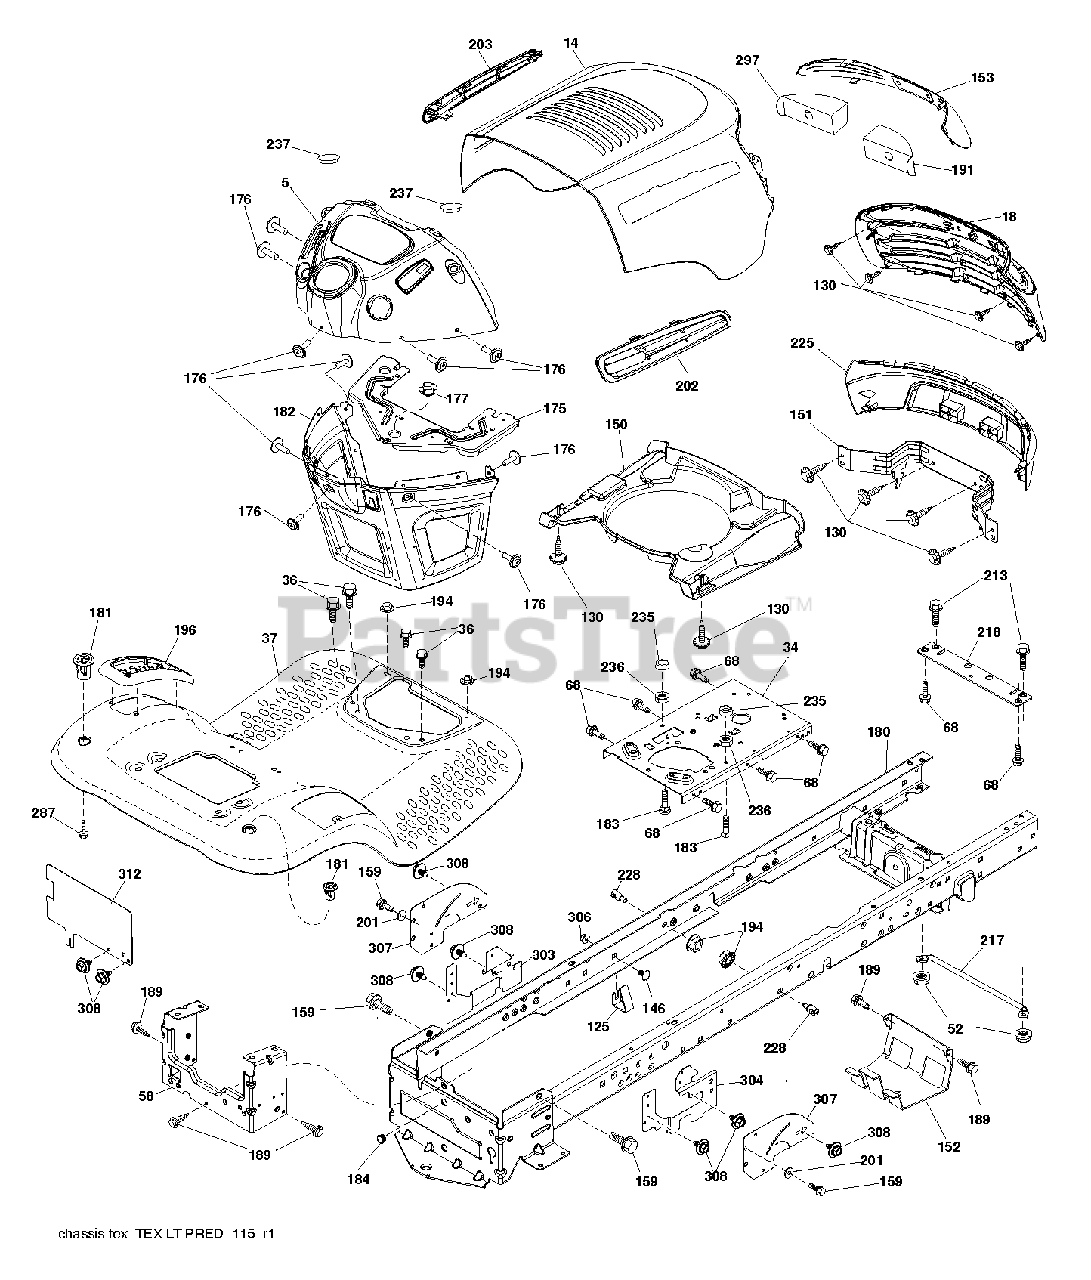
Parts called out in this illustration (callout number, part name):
36	SCREW 5/16"
52	LOCKNUT
58	DRAWBAR UPPER 2PC SMALL FENDER
125	Fuel Line Clip
130	SCREW.#10 X 0.750.BOS THREAD
146	BOLT.RDHD.SHT.SQNK.3
151	BRACKET.PIVOT.ALPHA.LT
152	SHIELD BROWNING
153	LENS.PREDATOR.LT
159	SCREW, 3/8-16X3/4
175	CROSSMEMBER
176	SCREW.#10-24X5/8.RN.QU
177	BUSHING STEERING
180	CHASS.WLDMNT.TL.12GA/2P.48/54
181	FEND/FTRST.PCH.CPH.NFW
182	DASH.LWER.PREDATOR/HUSQ.LT
183	BOLT.5/16-18X1-1/4 FULL THD
184	PLUG.DEMO.625
189	SCREW
191	INSERT.REFLECT.PREDATOR.LT.RH
194	NUT LOCK HEX FLANGE 5/16-18
196	CONSOLE.ASM.DECKLFT.BL/RBT.TLT
201	WASHER
213	BOLT
217	ROD.PIVOT.HOOD
218	X-PIECE.HOOD.STOP.NON/
228	STUD.FASTNER.W/ANTI-ROTATE
235	SPACER FENDER
236	NUT.CENTERLOCK.5/16-
237	PLUG.MOUNT.CARGO.BLK
297	REFLECTOR.INSERT.PRED.LH.LT
304	SHIELD.LWR.RH.LT30DECK.PNT.BLK
306	NUT LOCK FLG 3/8-16 UNC
308	BOLT, 5/16-18 X 1 3/4
